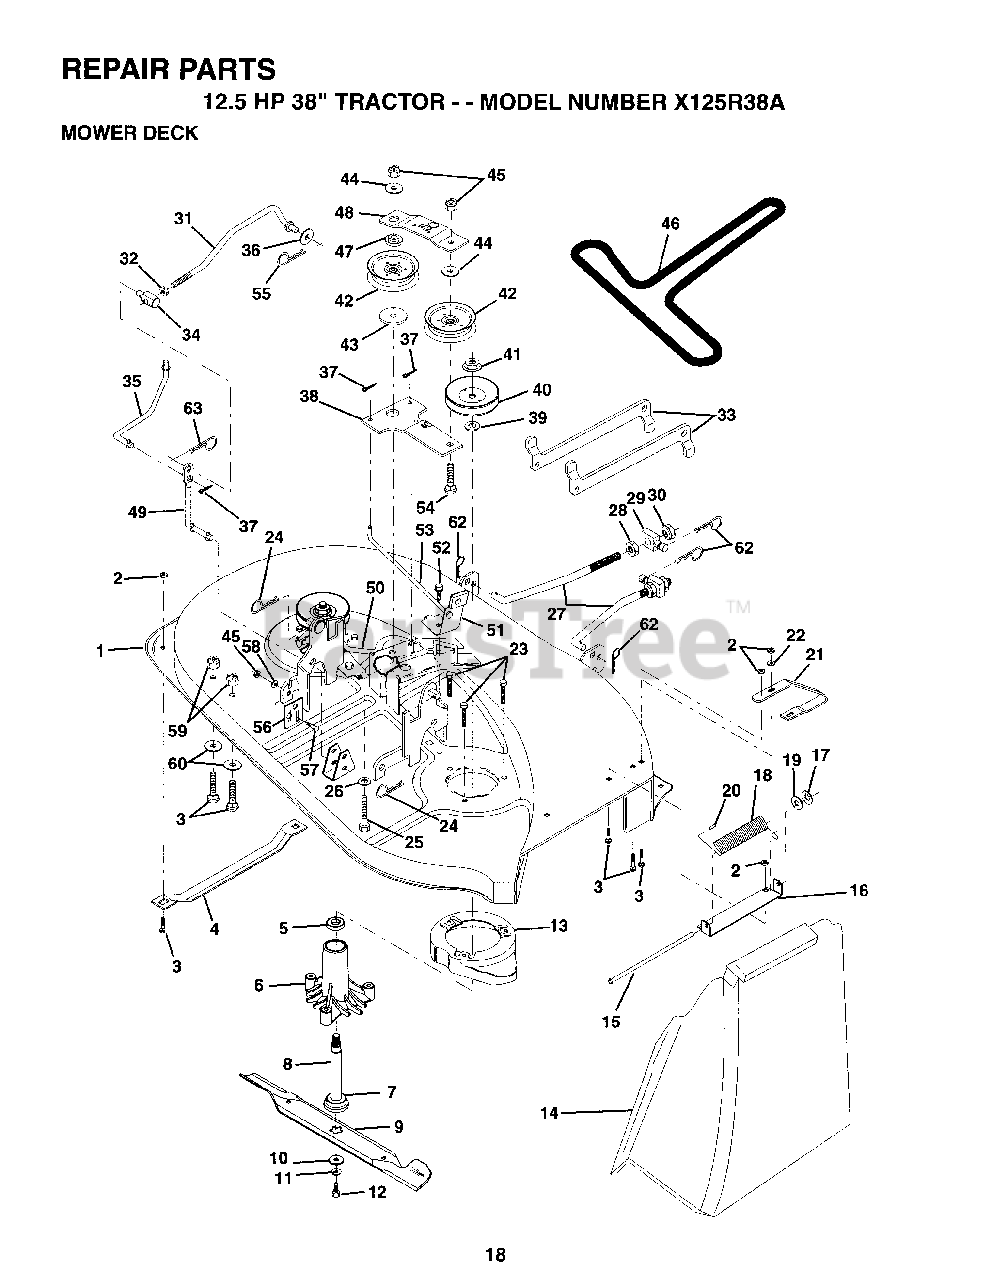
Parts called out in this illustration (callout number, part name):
3	BOLT
4	RUNNER-LH M
5	BEARING
6	HSG ASM MANDREL
7	BEARING.BALL
9	DECAL.HOOD.LH
10	WASHER BLADE
12	BLADE BOLT
14	DEFLECTOR-SHLD T
15	ROD-HINGE T
16	BRKT DEFLECTOR
17	NUT PUSH M
18	SPRING TORSION
19	WASHER
20	CAP-SLEEVE LT
21	RUNNER RH
22	WASHER M
25	BOLT
26	WASHER GT
27	"LINK ASM.,FRONT"
28	NUT
29	TRUNION
30	NUT.LK.W/WSH.1/2.
31	CLUTCH ROD PRI
32	NUT
33	SUSP ARM REAR
34	TRUNNION
35	CLUTCH ROD SEC
36	WASHER
38	IDLER ARM ASSY
39	WASHER
42	FLAT IDLER PULLEY
43	SPACER RETAINER
44	WASHER GT
46	BELT-V.88.12.MW
47	RETAINER SPACER
48	IDLER ARM STIFF
49	PIVOT ROD
50	BRAKE ROD LH
51	BRAKE ASM
52	SCREW
53	BRAKE ROD RH
54	BOLT
55	SPRING.RETAINER
56	PLATE ADJ LINK LH
57	BOLT
58	WASHER T
59	NUT
60	WASHER.34X.68X16
62	RETAINER.SPRING
63	RETAINER M
